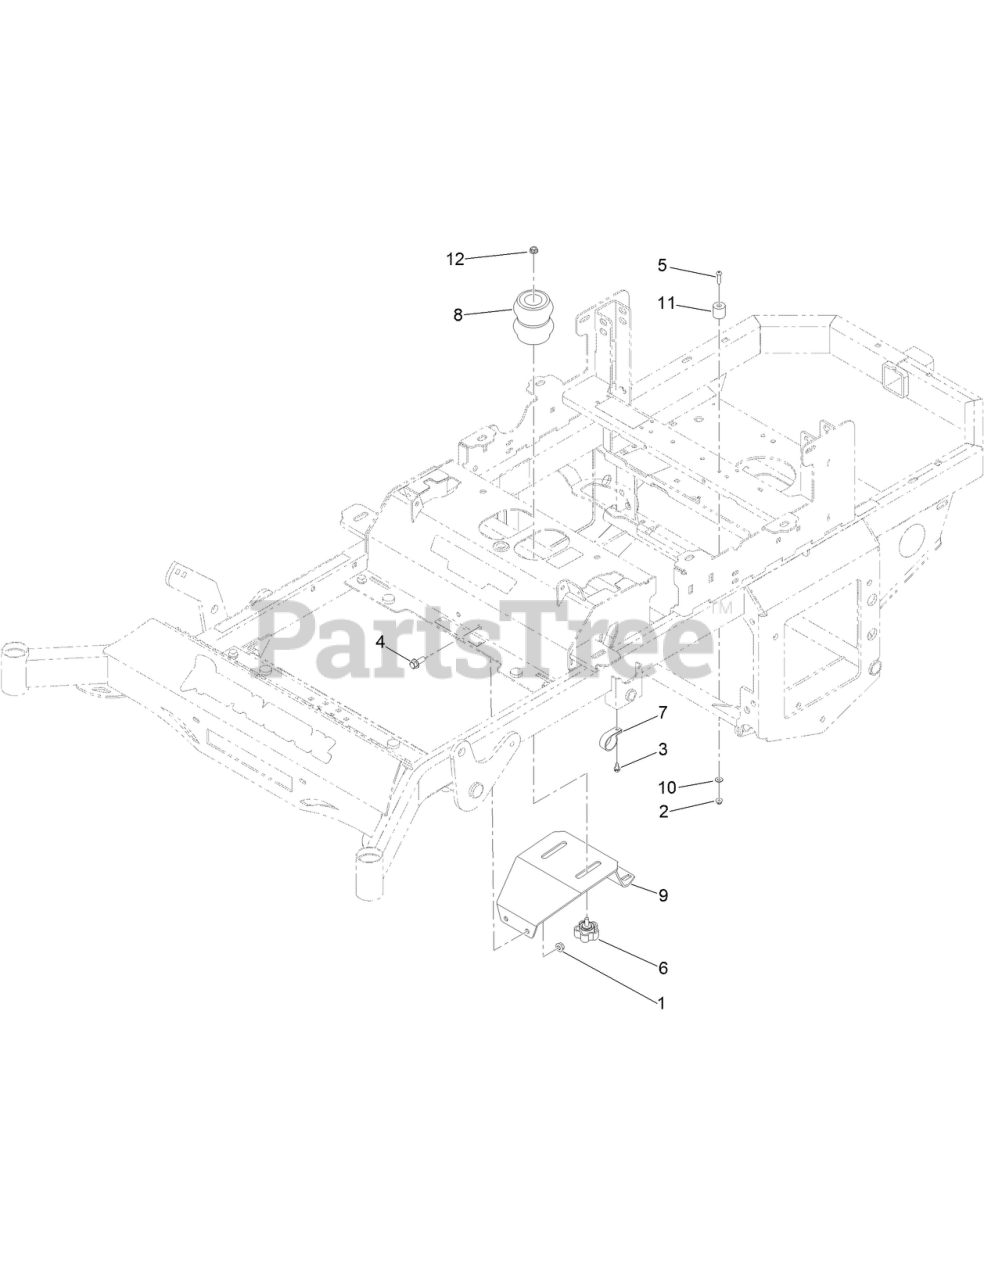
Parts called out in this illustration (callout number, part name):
1	3/8-16 HEX FLANGE NUT W/SERR ZINC
2	NUT-HF
3	SCREW-HWH
4	SCREW-HHF
5	1/4-20 X 1 BUTTON SOCKET C/S 18-8 SS
6	5/16-18X3/4 SL 5-LOBE MALE KNOB 1.90 DIA
7	1-1/4IN CUSHIONED LOOP CLAMP BLACK
8	SRT RR SUSP AND SEAT FT ELASTOMER TCB-3
9	MWR SEAT SUSP BRKT (SRT) PAINTED
10	WASHER-FLAT
11	HOOD REST RUBBER BUMPER
